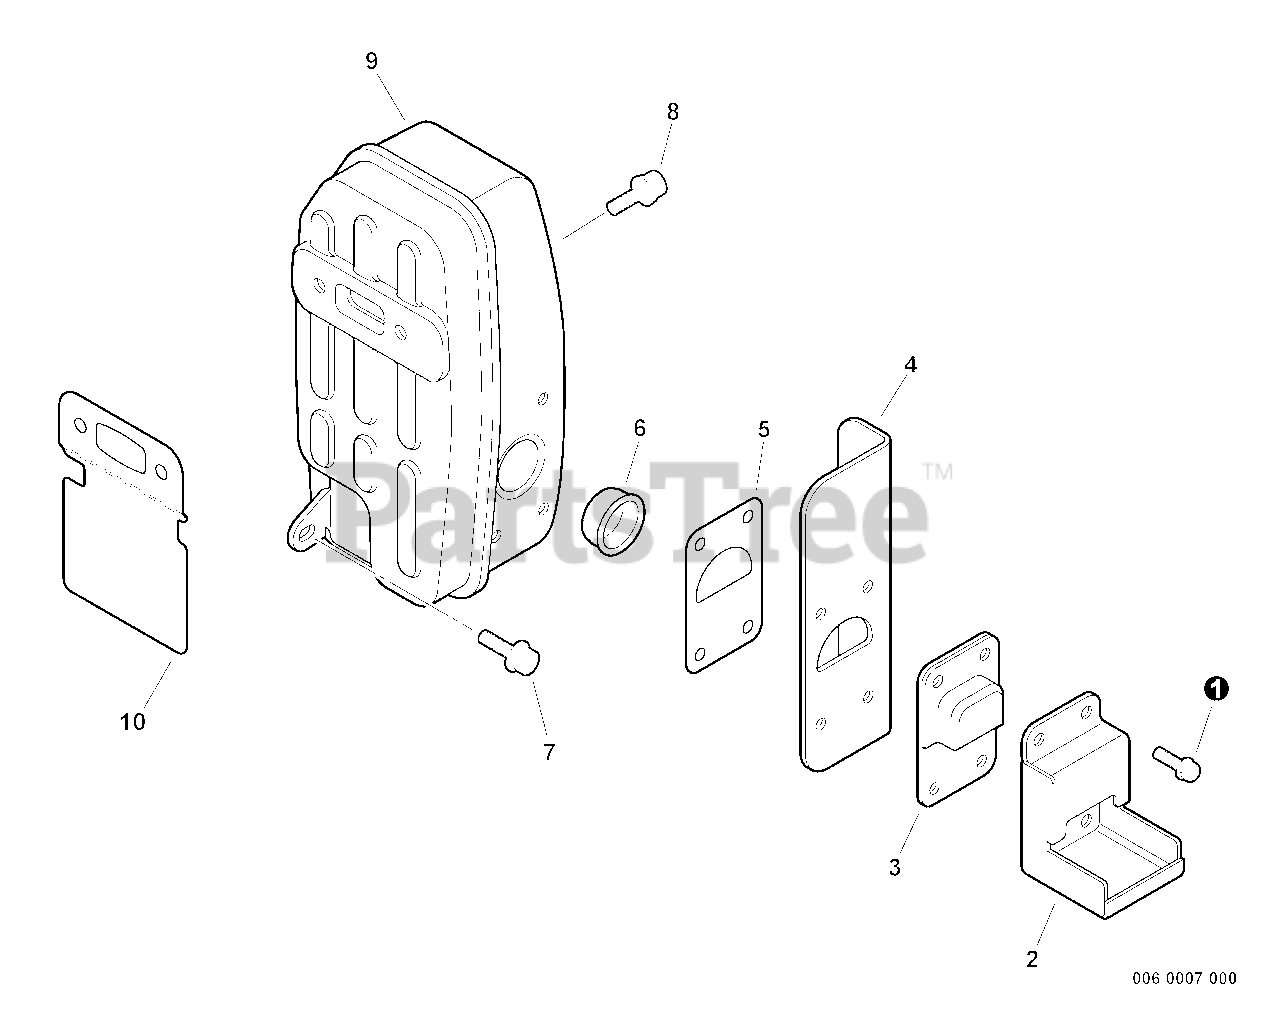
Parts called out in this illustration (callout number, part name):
1	SCREW - 4X14
2	GUIDE, EXHAUST - OUTER
3	GUIDE, EXHAUST - INNER
4	SHIELD, EXHAUST
5	GASKET, EXHAUST
6	SCREEN, SPARK ARRESTOR
7	SCREW - 5X14
8	SCREW - 6X20
9	MUFFLER
10	SHIELD, EXHAUST
